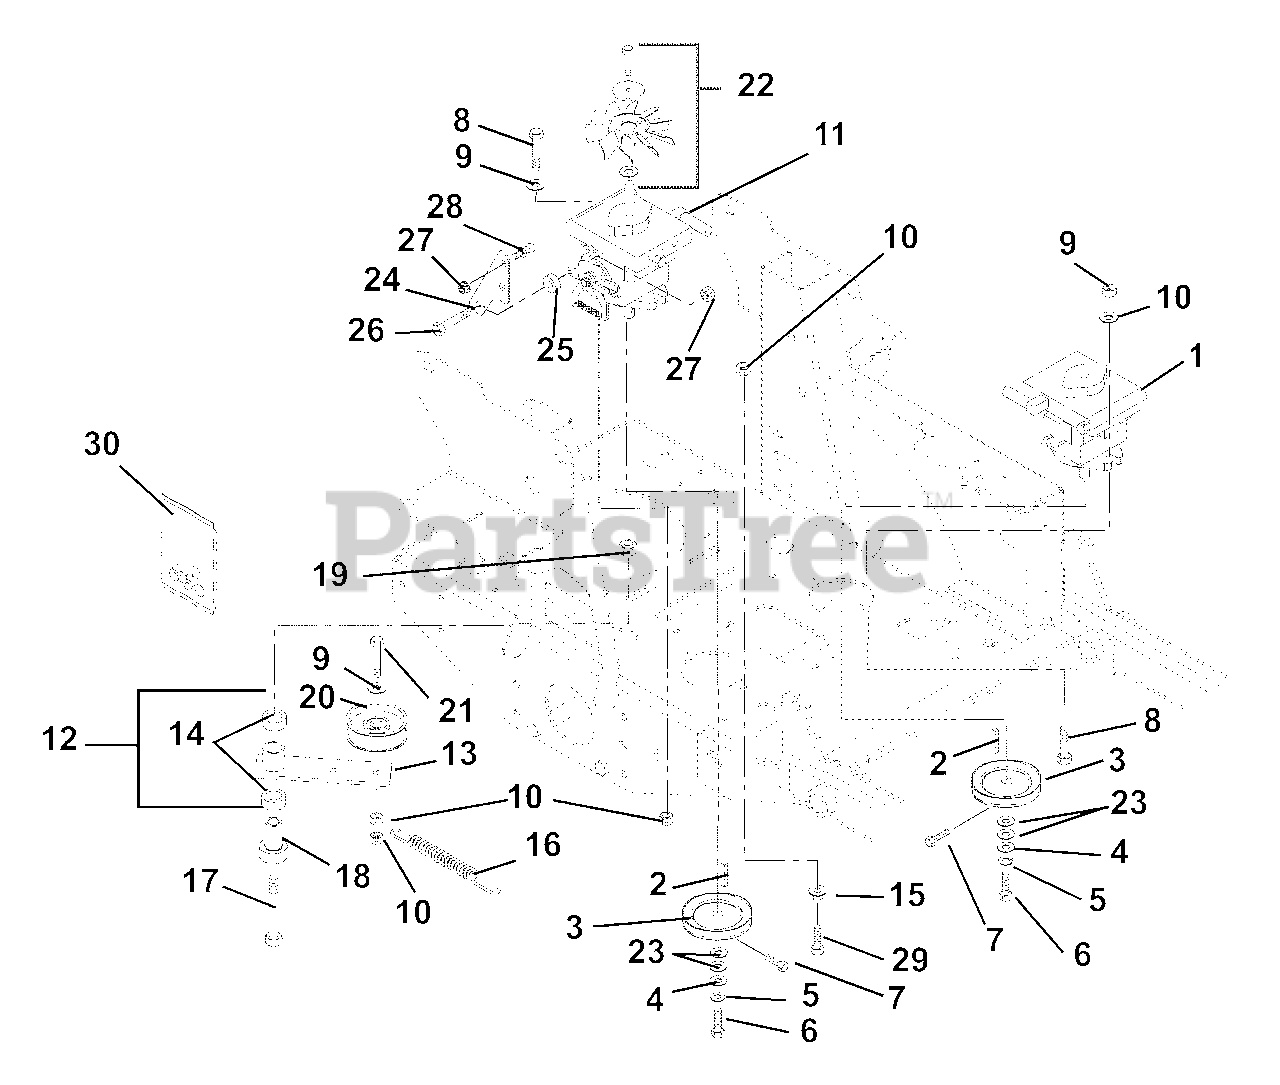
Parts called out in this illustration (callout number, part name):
1	Pump, Hydraulic BDP-10A Left Hand
2	Key, Straight 5mm x 25mm x 5mm
3	Sheave 4.0 x .199
4	Washer, Flat Steel .281 x 1.00 x .063
5	Washer, Locking .25 x .062
6	Bolt, Hex M6 x 1.00 x 12
7	Bolt, Hex .25-20 x .50 Grade 5
8	Bolt, Hex .38-16 x 1.25 Grade 5
9	Washer, Flat Steel .39 x .75 x .125
10	Nut, Locking Top Flange .38-16
11	Pump, Hydraulic BDP-10A Right Hand
12	Assembly,Idler Arm Guard Drive
13	Weldment, Idler Arm Ground Drive
14	Bearing, 1.00 x 1.12 x .75
15	Nut-Flange .375-16
16	Spring, Tension .120 x .845 x 6.50
17	Bolt, Hex .50-13 x 3.50 Grade 5
18	Bearing, Pedestal Powdered Metal
19	Nut, Locking Top Flange .50-13
20	Idler, Flat 4.00 x 1.06
21	Bolt, Hex .38-16 x 2.25 Grade 5
22	Fan, Cooling
23	Washer, Flat Steel .656 x 1.31 x .095
24	Bracket, Return to Neutral/Damper
25	Spacer .344 x 1.00 x .375
26	Bolt, Hex .31-18 x 1.25 Grade 5
27	Nut, Locking Top Flange .31-18
28	Stud, Ball
29	Bolt, Hex .38-16 x 3.25 Grade 5
30	Kit, Pump Seal (BDP-10A)
